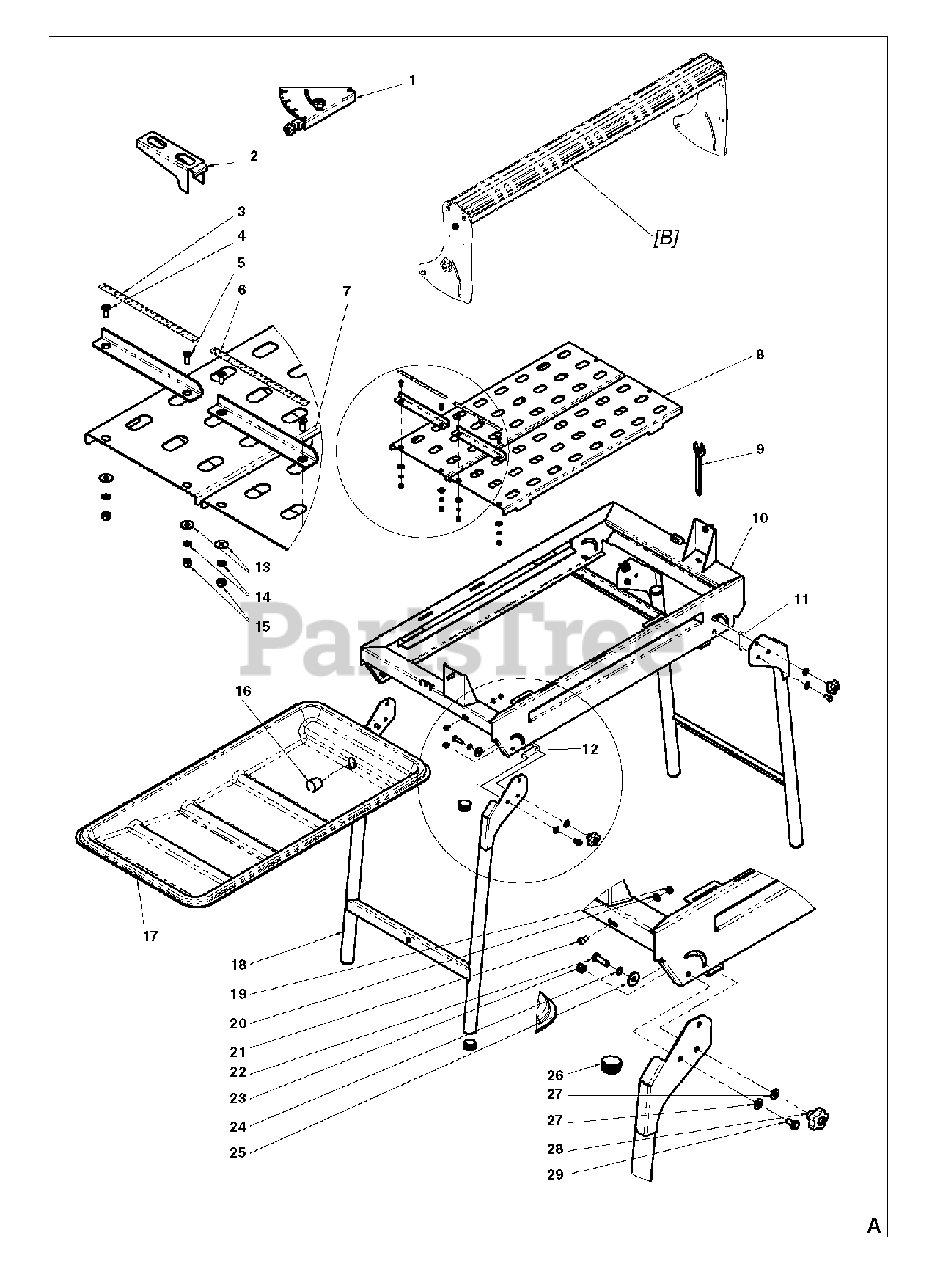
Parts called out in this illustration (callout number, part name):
4	SCREW CRCSFM
5	SCREW CRCSFM
19	NUT
20	RONDELLE ACIER M6 BICHRO/
29	VIS TH 8/8 8X16 BICHROM/
